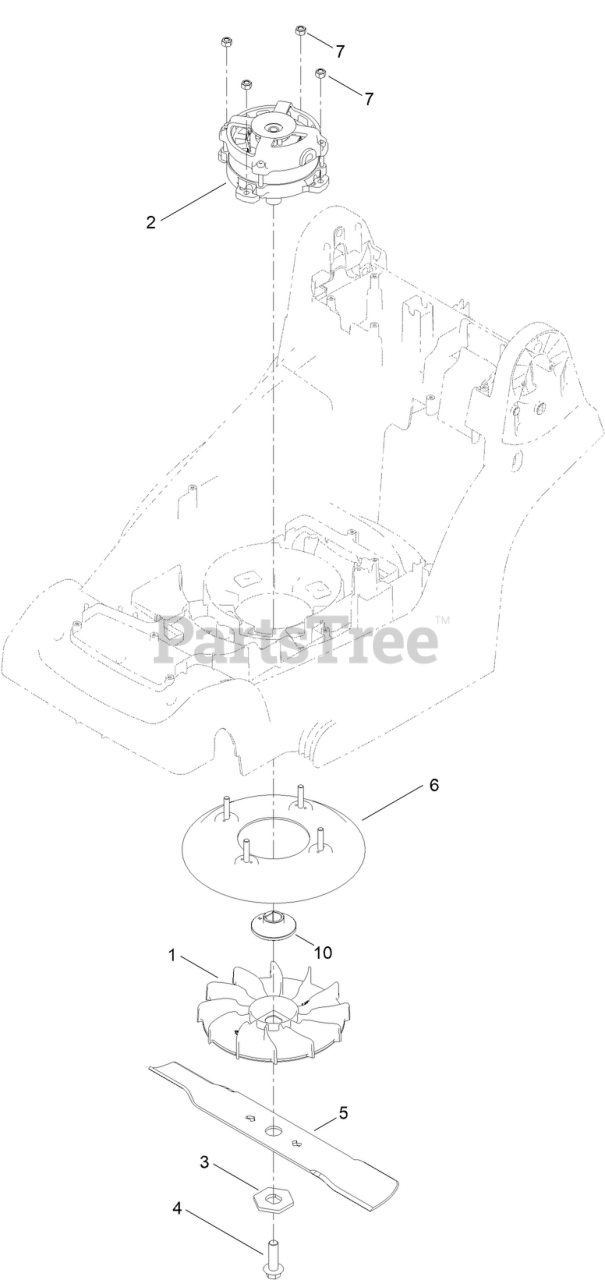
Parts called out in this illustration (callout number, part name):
1	FAN, SQUARE HOLE
2	MOTOR, BRUSHLESS, 60V, 600W
3	WASHER, HEX
4	BLADE BOLT
5	BLADE, MULCH, 36CM
6	BLADE COVER
7	NUT, NYLOC, M6X1
10	BOSS, BLADE SINTERED
